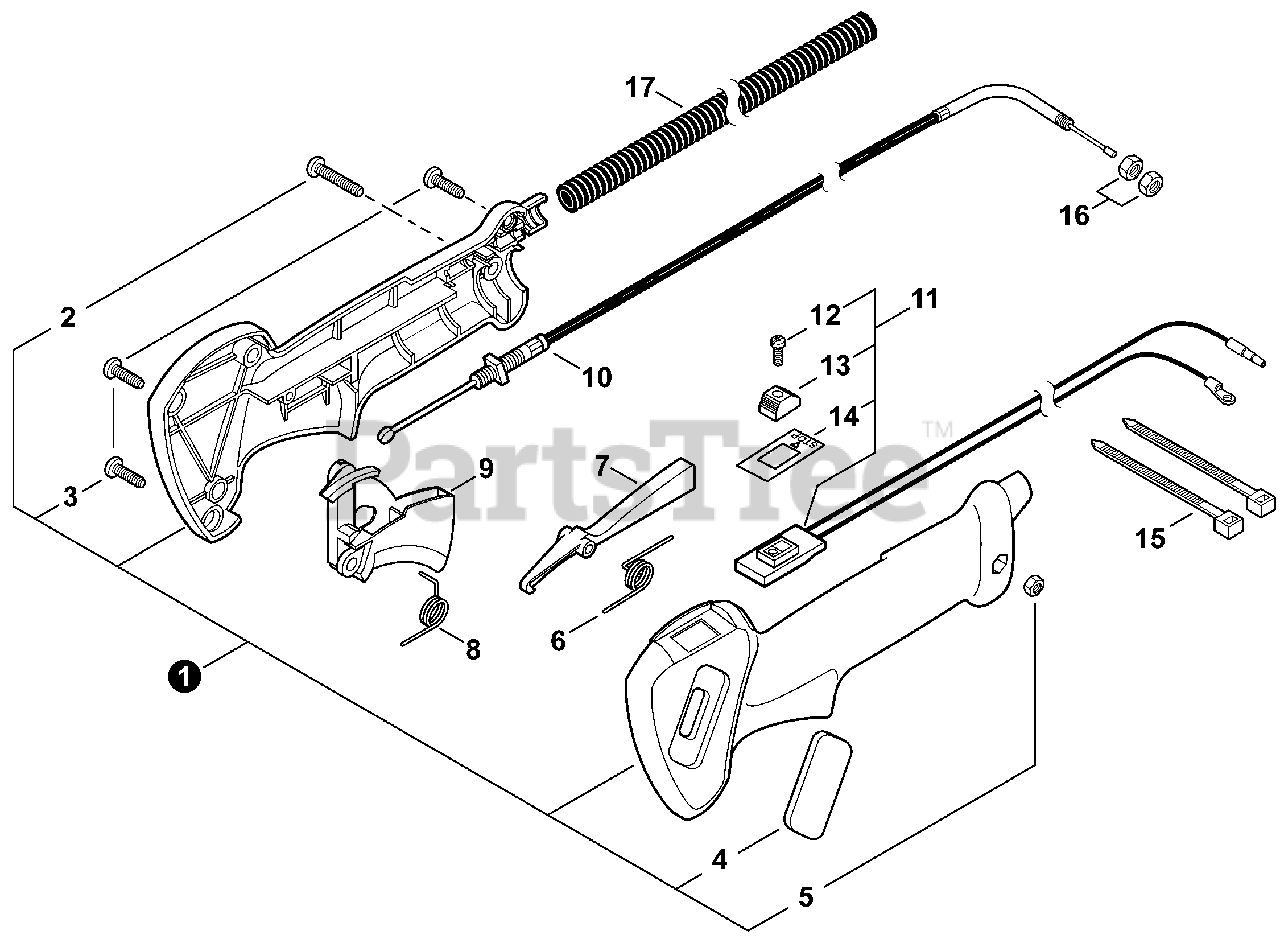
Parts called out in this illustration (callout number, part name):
1	GRIP ASSY, THROTTLE
2	SCREW 5×30
3	SCREW 4×16
5	NUT M5
6	SPRING, TORSION
7	LOCKOUT, THROTTLE
8	SPRING, TORSION
9	TRIGGER, THROTTLE
10	CABLE, THROTTLE
11	SWITCH, ON-OFF
12	SCREW 3×10
13	KNOB, SWITCH - ORANGE
14	LABEL, SWITCH
15	TIE, CABLE
17	TUBE, FLEXIBLE
